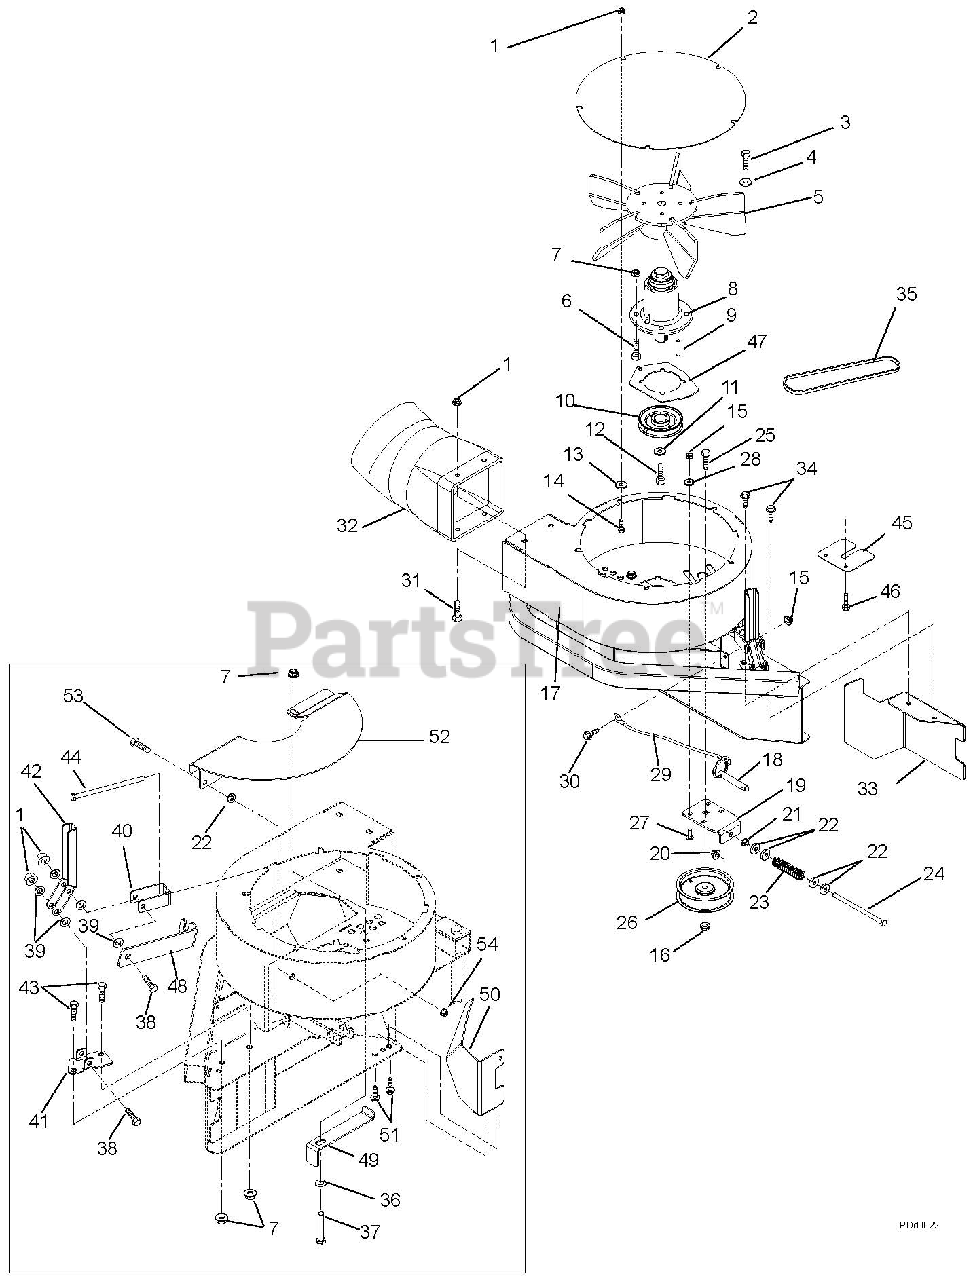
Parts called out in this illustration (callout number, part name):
1	Nut, .31-18 Nyloc Flange
2	Cover, Blower
3	Bolt, Hex .62-18 x 1.75
4	Washer, Bevelled .63 x 1.625 x .14
5	Weldment, Impeller
6	Bolt, Hex .38-16 x 1.25 Grade 5
7	Nut, .38-16 Nyloc Flange
8	Maintenance Free Spindle Assembly
9	Key, Square .25 x .25 x 1.00 RC 40-50
10	Weldment, Pulley-V 3.50 x 1.004 with Key
11	Washer, Flat Steel .39 x 1.5 x .125
12	Bolt, Hex .38-16 x 1.00 EP30
13	Nut, Push .312
14	Bolt, Round Head Square Short Neck .31-18 x .75 Grade 5
15	Nut, Locking Top Flange .25-20
16	Nut, .38-16 Nyloc Flange
17	Weldment, Blower Housing
18	Pin, Spring Ball .375OD x 1.50
19	Bracket, Adjustable Idler
20	Nut, .31-18 Nyloc Flange
21	Nut, Spin Lock-Flange .312-18
22	Washer, Flat Steel .38 x .87 x .179
23	Spring, Compression .092 x .77 x 3.13
24	Bolt, Hex .31-18 x 5.50 Grade 5
25	Bolt, Hex .38-16 x 1.75 Grade 5
26	Pulley, Idler 4.00
27	Bolt, Round Head Square Neck .25-20 x .75 Grade 5
28	Bushing, Flange .265 x .437 x .250 x .750
29	Cable, Hood
30	Bolt, Hex .25-20 x .75 Grade 5
31	Bolt, Hex .31-18 x .75 Grade 5
32	Adapter, Hose
33	Baffle, Blower 44/48"
33	Baffle, Blower 52"
33	Baffle, Blower 60"
34	Screw, Tapping .38-16 x .50 Hex Washer Head
35	V-Belt, 44" and 48" Mower Deck
35	V-Belt, 52" Mower Deck
35	V-Belt, 60" Mower Deck
36	Washer, Flat Steel .406 x .812 x .065
37	Bolt, Hex .38-16 x 1.00 Grade 5
38	Bolt, Hex .31-18 x 2.00 Grade 5
39	Washer, Flat – Nylon .375 x .75 x .060
40	Link, Idler Release
41	Mount, Idler Release Lever
42	Lever, Idler Release
43	Bolt, Hex .38-16 x .75 Grade 5
44	Bolt, Hex .31-18 x 5.50 Grade 5
45	Finger Guard 44-, 48-, and 52-Inch Deck
45	Finger Guard 60-Inch Deck
46	Bolt, Hex .25-20 x .50 Grade 5
47	Plate, Bearing Housing Support
48	Lock, Idler Release Lever
49	Finger – Belt
50	Baffle, Blower – Rear – 52"/60"
51	Screw, Tap .38-16 x .50
52	Cover, Bottom Plate
53	Bolt, Hex .31-18 x 0.75
54	Nut, Nyloc Flange .31-18
